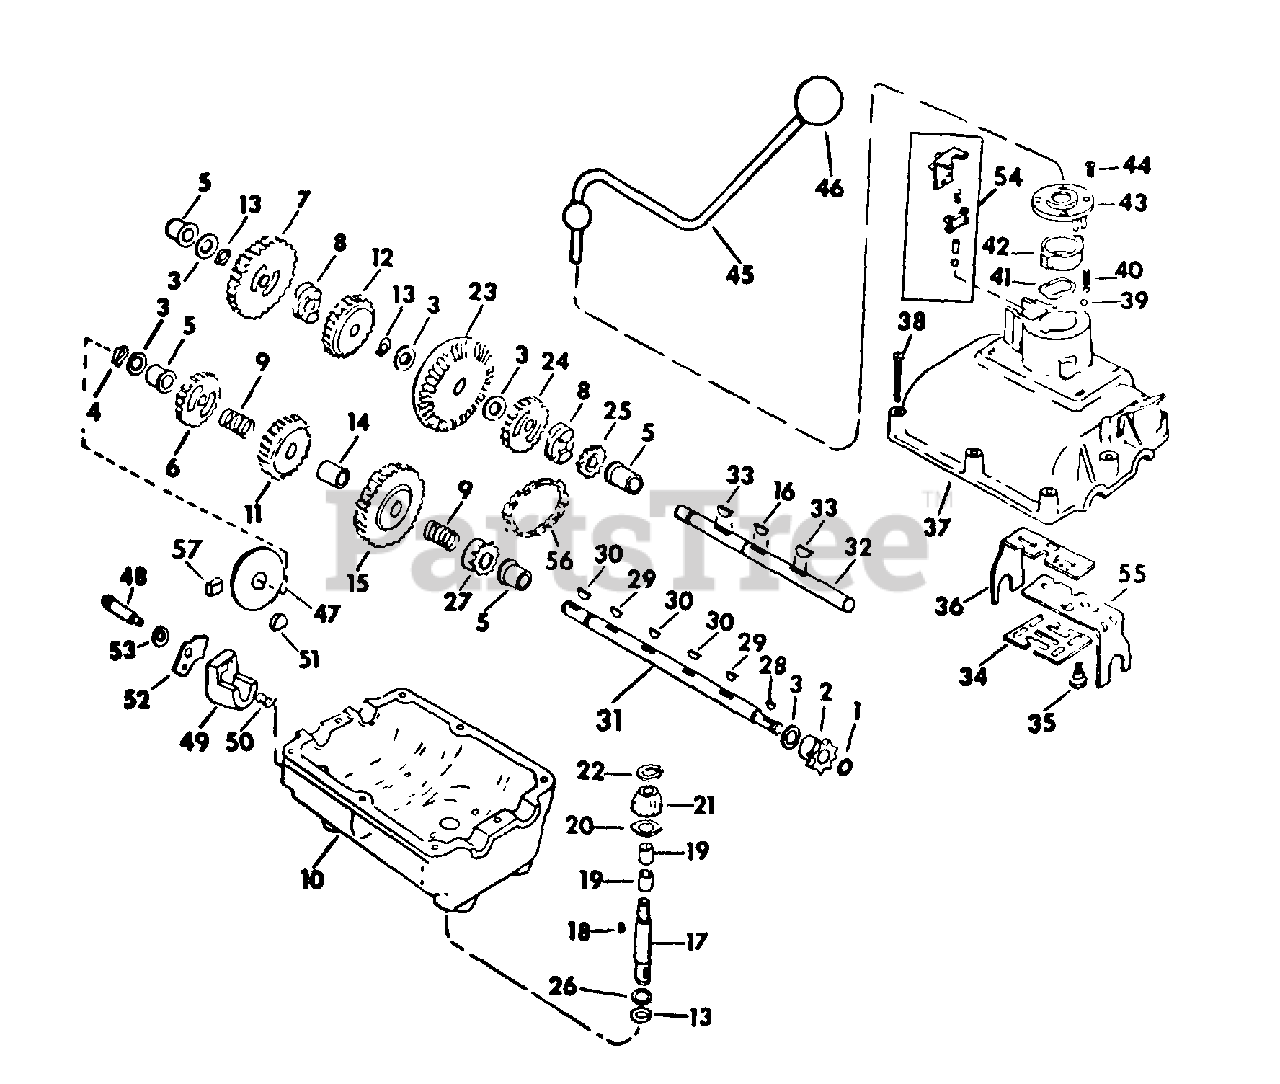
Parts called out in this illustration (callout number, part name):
1	RING, 461 INV EXT RET
2	SPROCKET, 8 T
3	WASHER, PLAIN .030
4	E-RING, 480 EXT RET
5	BEARING, FLANGE
6	GEAR, SPUR -20T
7	GEAR W/SPACER, SPUR -30 T
8	COLLAR, CLUTCH
9	SPRING, COMPRESSION
10	HOUSING, LOWER
11	GEAR W/SPACER, SPUR -25 T
12	GEAR W/SPACER, SPUR -25 T-
13	RING, .579 EXT RET
15	GEAR, SPUR -30 T
16	KEY. 3/16 X 3/4 WOODRUFF 9
17	SHAFT KIT, INPUT
18	KEY, 3/32 X 1/2 WOODRUFF 2
19	BEARING, NEEDLE
20	WASHER, THRUST .093
21	PINION, BEVEL -16 T
22	RING, 461 EXT RET
23	GEAR, BEVEL -42 T
24	GEAR, SPUR -20 T
25	SPROCKET, SPECIAL -12 T
26	WASHER, .656 X 1.000 X .054 PLN
27	SPROCKET, SPECIAL -12 T
28	KEY, WOODRUFF NO. 4 SPECIAL
29	KEY, 1/8 X 1/2 WOODRUFF 3
30	KEY, 3/16 X 5/8 WOODRUFF 61
31	SHAFT, OUTPUT
32	SHAFT W/RING, IH-269174-R1, DRIVE
33	KEY, HI-PRO SPECIAL
34	PLATE, LOCK-OUT
35	SCREW, SHOULDER
36	FORK, SHIFTER LH
37	HOUSING, UPPER
38	SCREW, TAPPING
39	BALL, 3/16 CR-STL DETENT
40	SPRING, DETENT
41	WASHER, WAVE
42	INSERT, NYLON
43	COVER, NYLON
44	SCREW, 10-24 X 1/2 C-Z CR REC PAN HD TAP
45	HANDLE ASSY, SHIFTER
46	KNOB, SHIFTER
48	BOLT, SHOULDER
49	KIT, BRAKE ASSY
50	SPRING, COMPRESSION
51	PUCK, FRICTION
52	LEVER ASSY, ACTUATING RH
53	WASHER, PLAIN .015
53	WASHER, PLAIN .006
54	KIT, SWITCH ASSY
55	FORK, SHIFTER RH
56	CHAIN, ROLLER
57	PUCK, FRICTION
